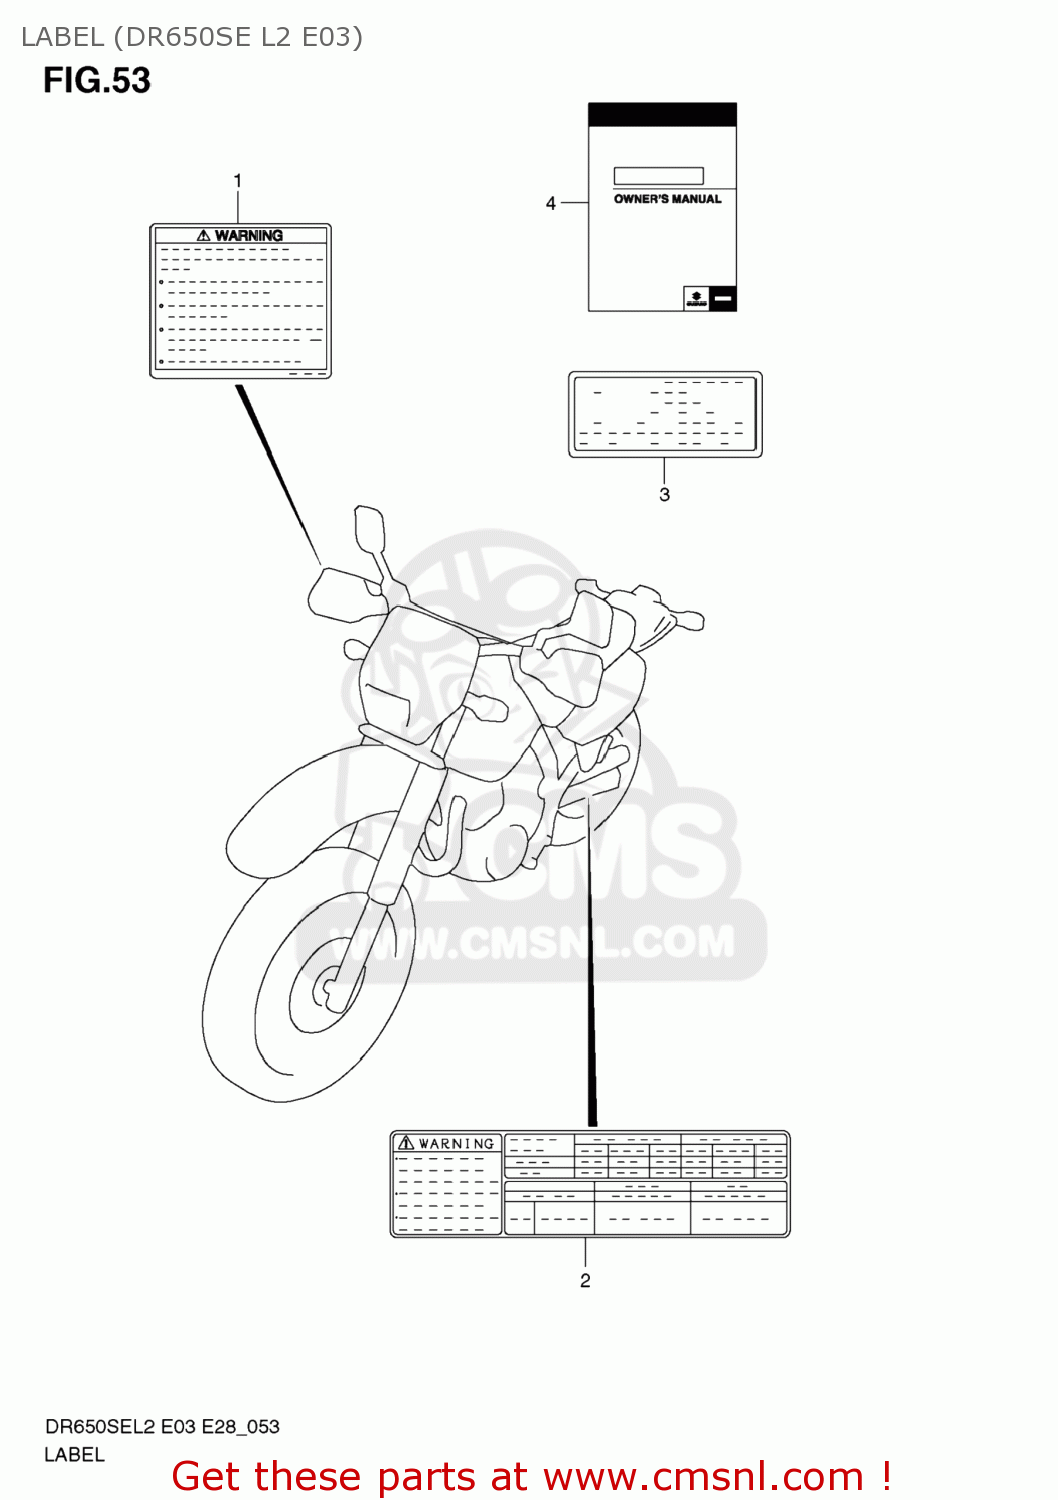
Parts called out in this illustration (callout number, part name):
1	LABEL,GENERAL WARNING
2	LABEL,TIRE INFORMATION
3	LABEL,MANUAL NOTICE
4	MANUAL,OWNER'S
